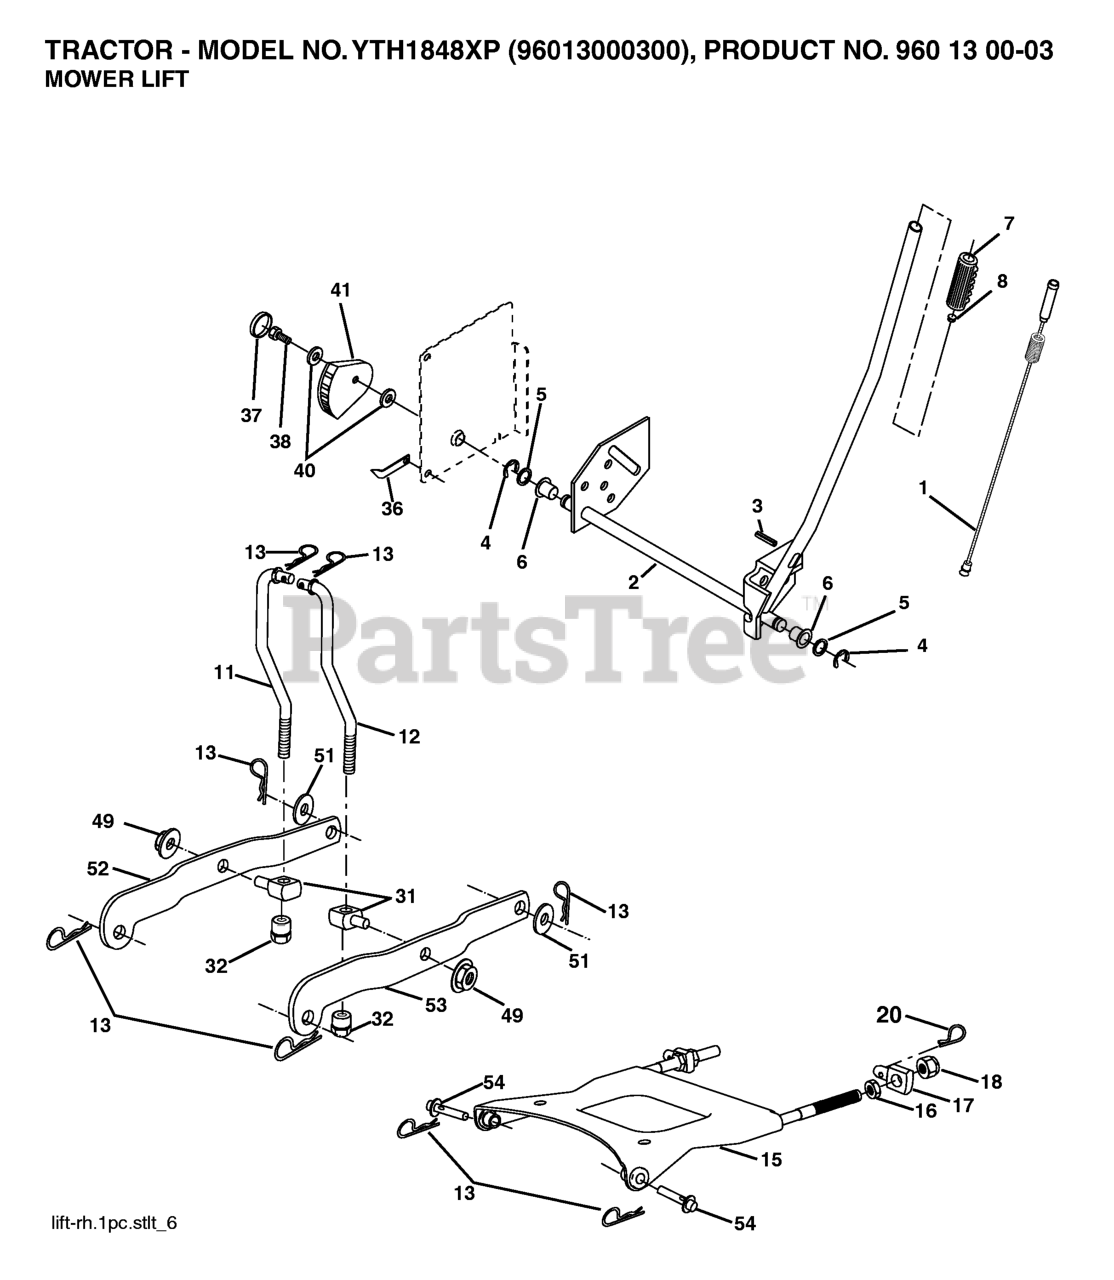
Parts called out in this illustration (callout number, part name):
1	WIRE ASM INNER W/ PLUNGER LT
2	SHAFT ASM R HANDLE
3	PIN GROOVE.
4	RETAINING RING LT
6	BEARING.NYLON
7	GRIP HANDLE
8	PLUNGER BUT KIT
11	LIFT LINK LH
12	LIFT LINK RH
13	RETAINER-SPRNG RB
15	PLATE ASM SUSP FRONT
16	NUT.HEX.JAM.1/2-13
18	NUT.LK.W/WSH.1/2.
20	SPRING RETAINER
26	RETAINER CLIP
27	ROD ADJ LIFT
28	NUT
29	KNOB INF 3/8-16
32	NUT, LIFT LINK 7/16-20
36	POINTER, HEIGHT INDICATOR(2 2)
38	SCREW 5/16-18X1
41	IND. HEIGHT STLT
49	NUT
50	NUT PUSH M
51	Washer 1 17/32 X 7/8 X 16 Ga
52	ARM SUSP. REAR LH
53	ARM SUSP REAR RH
54	PIN.FLANGE
